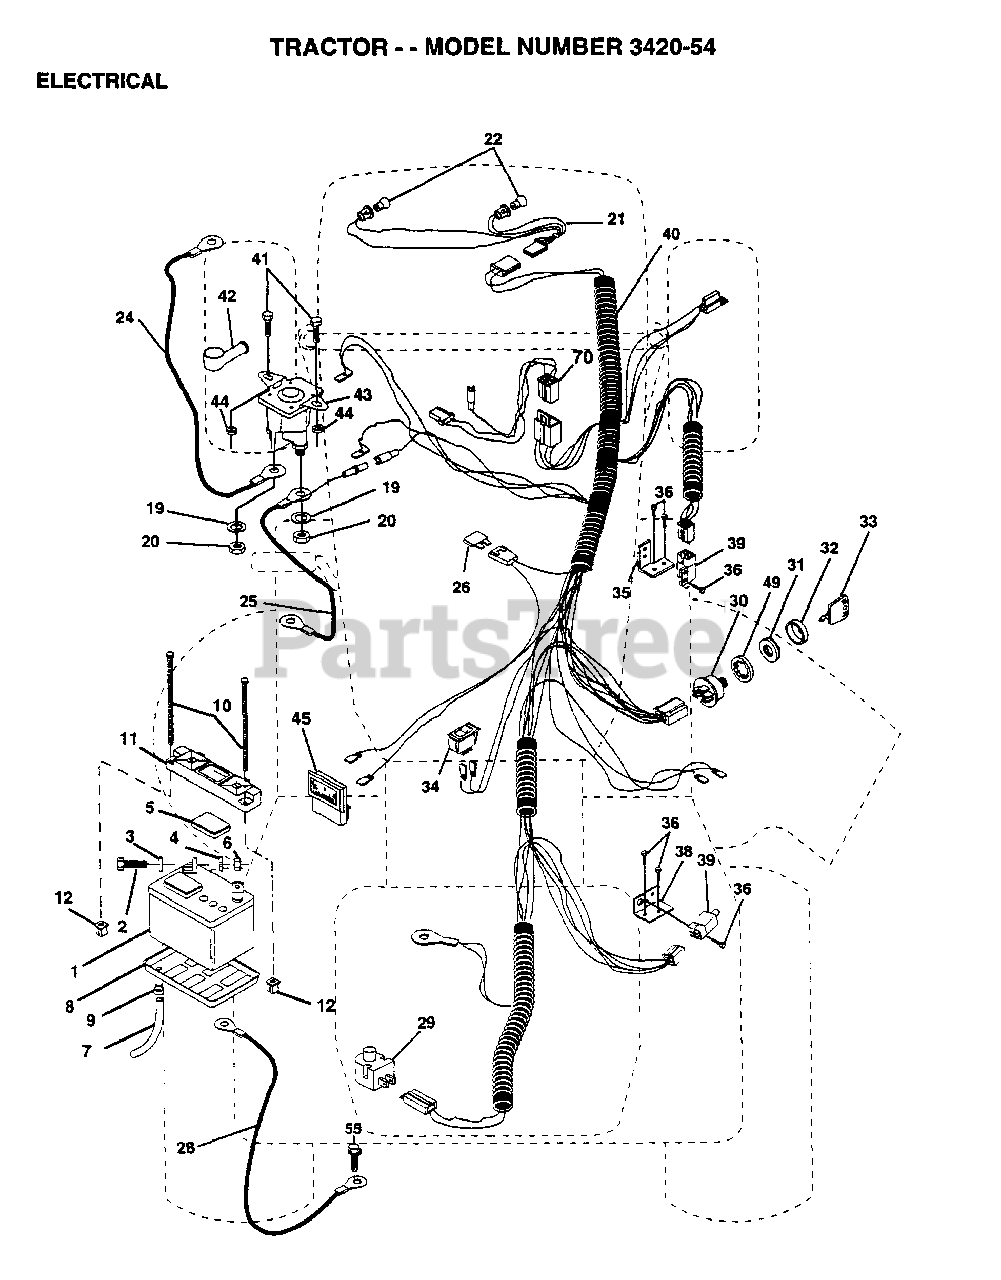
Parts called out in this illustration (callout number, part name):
2	BOLT LT
3	WASHER
4	LOCKWASHER
5	"CAP,BATTERY "
7	"DRAIN TU T, BATT"
8	"TRAY T, BATTERY"
9	HOSE CLAMP T
12	NUT WING PLSTC 1/4-20
20	NUT
21	"HARNESS,LIGHT SOC"
22	HEADLAMP BULB
24	CABLE.6GA.22W/16W
25	"CABLE T, BATTERY"
26	FUSE HYT
28	CABLE.GRND.6GA.21
29	SWITCH SEAT
32	COVER KEY SWITCH
33	KEY MLD GEN DELTA
34	SWITCH LT
35	BRACKET LT
36	SCREW
38	BRACKET SWITCH IN
39	SWITCH INTERLOCKT
40	HARNESS.IGN.MECH.
41	BOLT.HX.1/4-20
44	NUT
49	LOCKWASHER
55	SCREW LT
70	HARNESS ENG DUAL
